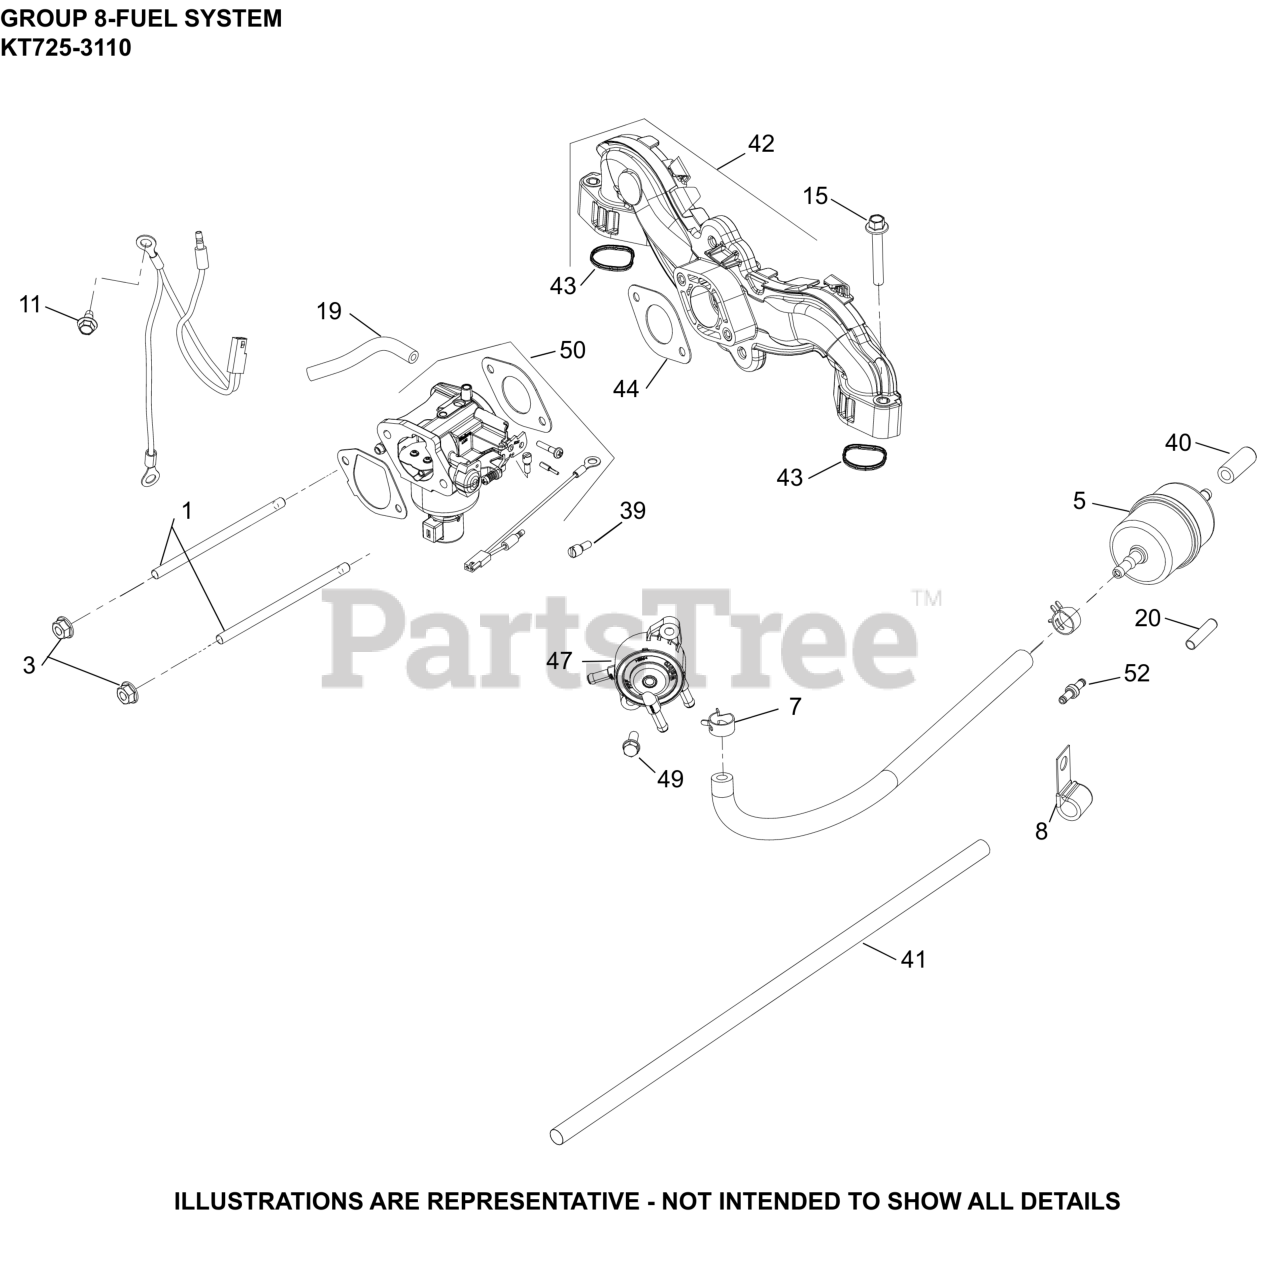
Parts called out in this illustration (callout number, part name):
3	NUT, FLG M6X1.0
5	FILTER, FUEL
7	SPRING CLAMP, HOSE
8	CLIP, CABLE (KM)
11	SCREW, THREAD FORMING
15	SCREW, FLG M6X1.0X40
19	HOSE, EVAPORATIVE 20"- (#24326143S)
20	CAP, MASKING
39	SCREW, THROTTLE STOP
40	MASKING CAP
41	SLEEVE, ANTI-ABRASION
42	INTAKE MANIFOLD W/GASKETS
43	O-RING, INTAKE PORT
44	GASKET, CARBURETOR (PIM, CV)
47	PUMP, FUEL (PULSE)
49	SCREW, HEX HEAD
50	KIT, CARBURETOR COMPLETE
52	FITTING, FUEL SYSTEM
NI	KIT,REPAIR OVERHAUL(WALBRO)
NI	KIT,BOWL O-RING(WALBRO)
NI	KIT, HIGH ALT (4000-8000 FT)WALBRO)
NI	KIT,SOLENOID REPAIR(WALBRO)
NI	KIT,REPAIR FLOAT(WALBRO)
